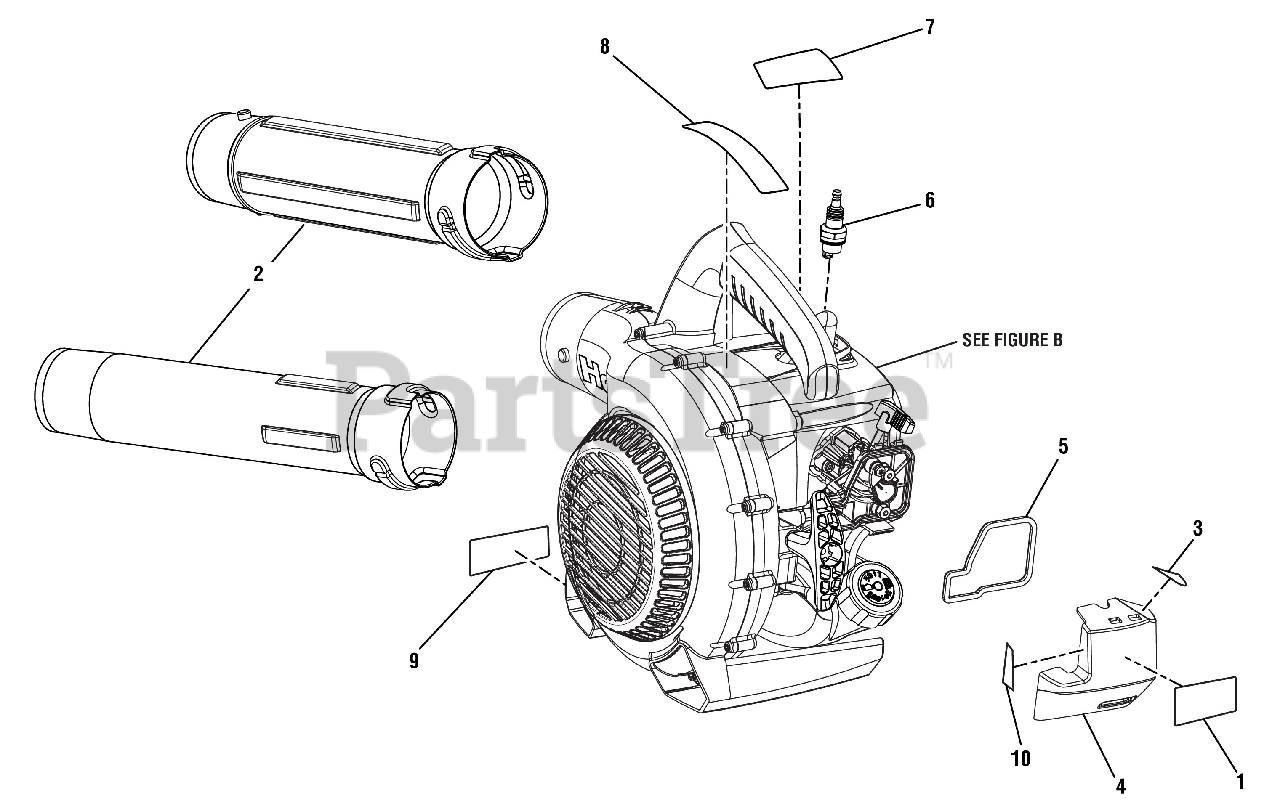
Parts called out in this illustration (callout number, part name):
1	Starting Instructions Label
2	Sweeper Nozzle & Upper Blower Tube Assembly
3	Throttle Label
4	Air Box Cover w/Label
5	Air Box Gasket
6	Spark Plug (Champion RCJ6Y)
7	Logo Label (Engine Shroud)
8	Warning Icon Label
9	Warning Label (Combustion)
10	Choke Label
